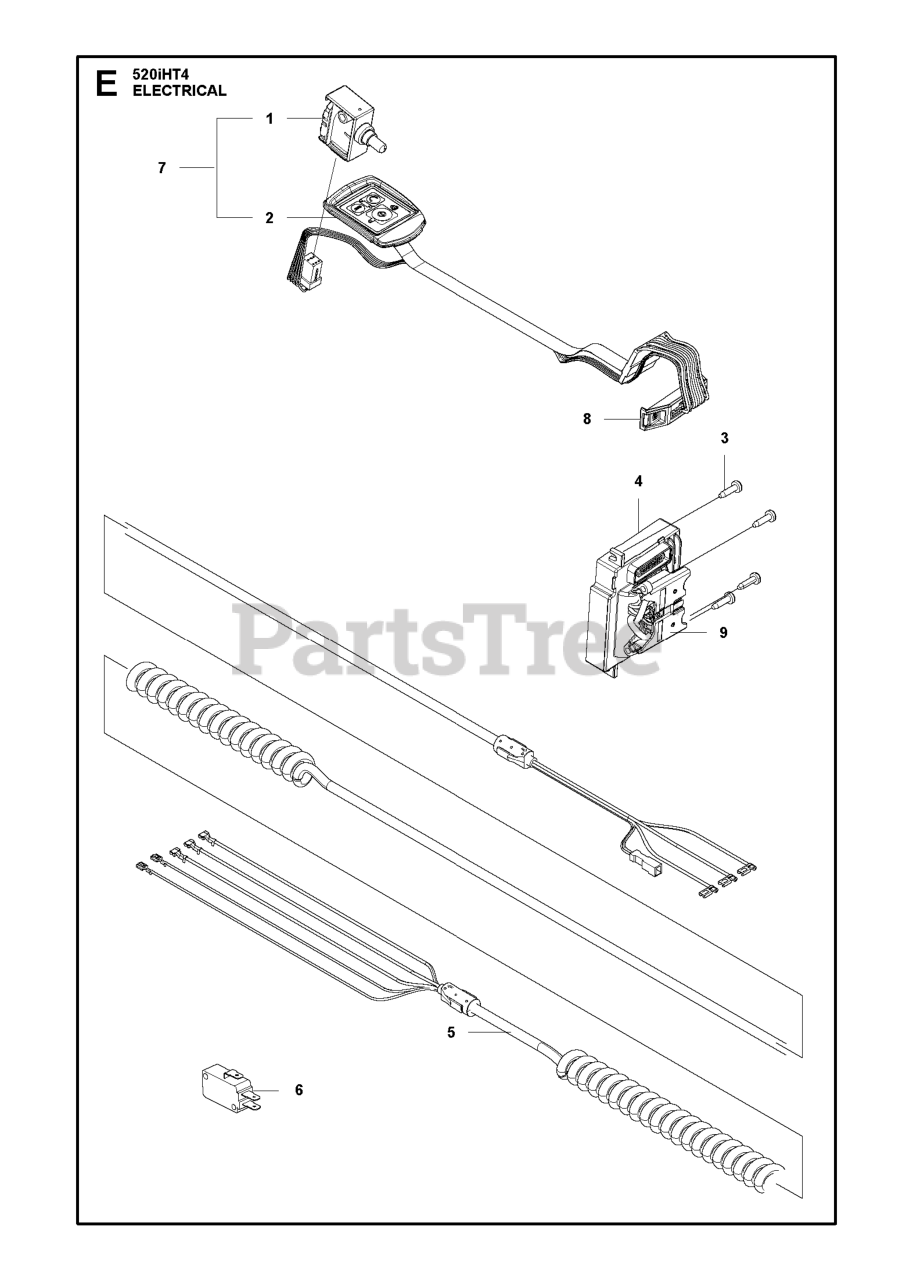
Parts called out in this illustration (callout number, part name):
1	TRIGGER SWITCH IPX4
2	WIRING ASSY POLE HEDGE MAIN
3	SCREW CITXPANT
4	CONTROL UNIT BLDC - 536LIHE3
7	SWITCH KIT BATTERY POLE HEDGER
9	CONNECTOR BATTERY
